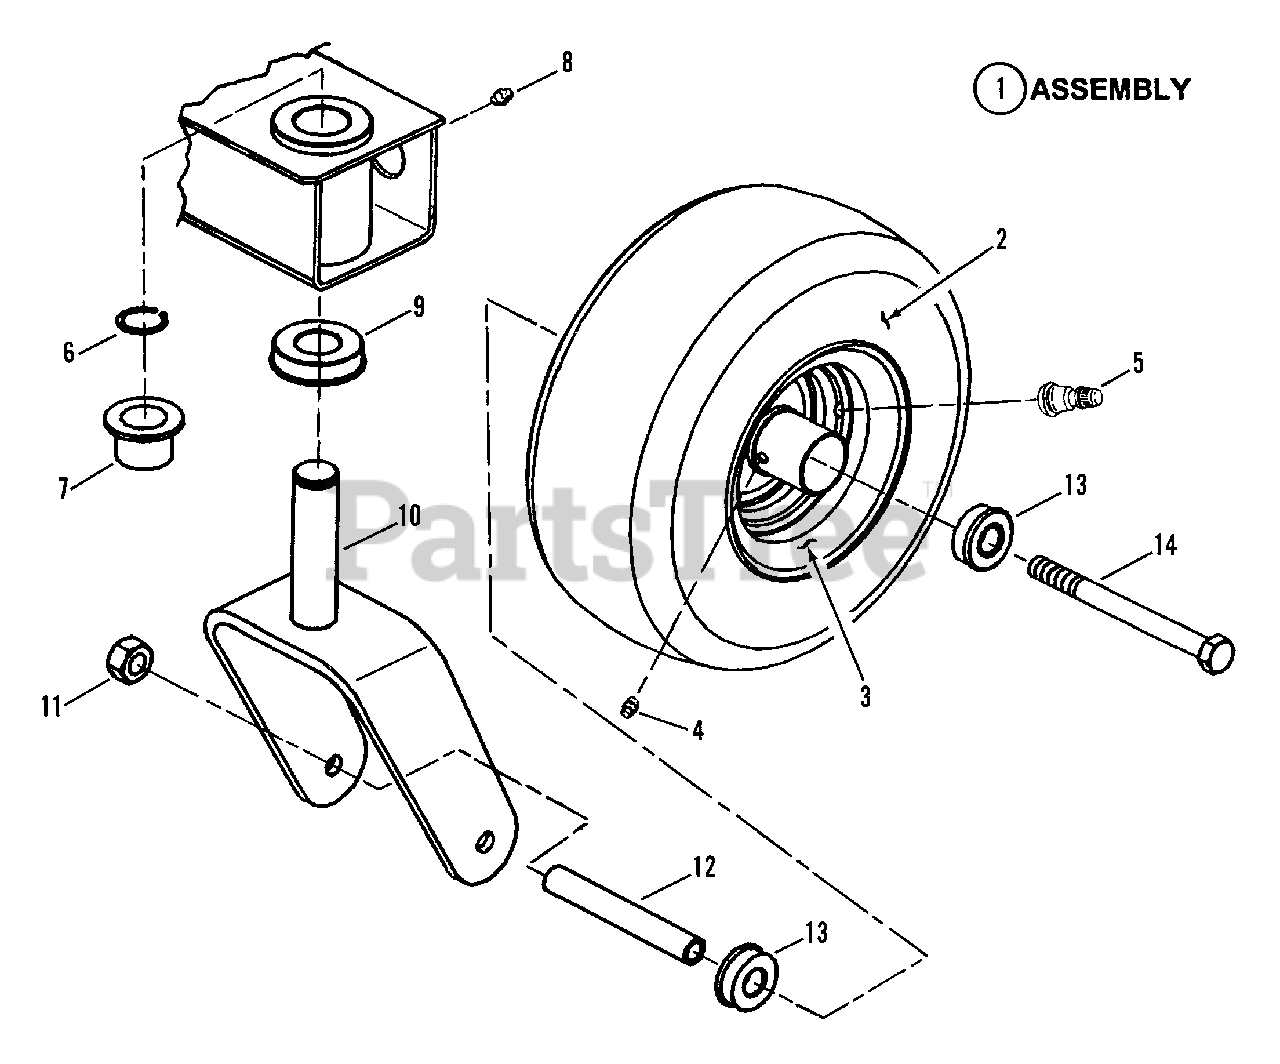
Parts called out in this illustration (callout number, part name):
1	ASSEMBLY, Front Wheel & Tire (Complete)
2	TIRE, 11 x 4.00-5, Smooth Tread
3	RIM, Caster Wheel
4	FITTING, Lube
5	VALVE, Air (Snap-in)
6	RING, 1" External Retaining
7	BUSHING, Caster
8	LUBE FITTING, Straight (press-fit for .187 dia. Hole)
9	BEARING, Flanged 1 x 2 x 5/8"
10	CASTER, Pivot Yoke
11	NUT, 7/16-14 Hex Center Lock
12	TUBE, 5/8 O.D. x 14 Ga. x 4.51
13	BEARING, Ball 5/8 x 1-3/8"
14	SCREW, 7/16-14 x 6" Hex Head Cap, Grade 5
